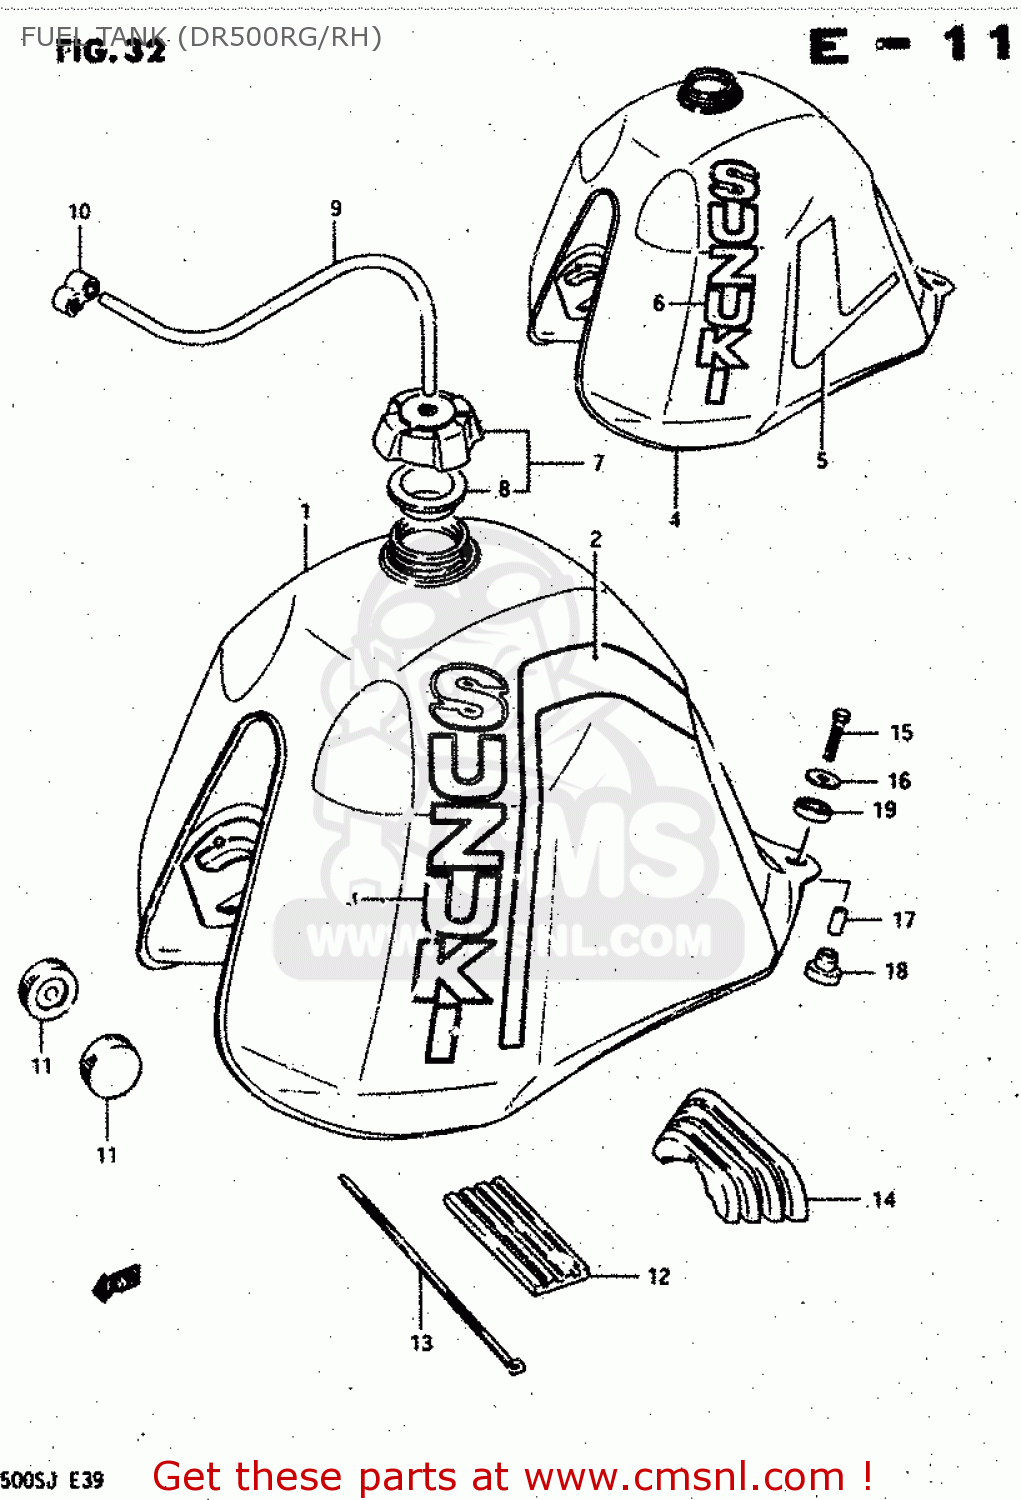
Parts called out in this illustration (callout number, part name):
1	TANK ASSY, FUEL
2	TAPE SET, FUEL TANK
3	EMBLEM
4	TANK ASSY, FUEL
5	TAPE SET, FUEL TANK (BLUE)
6	EMBLEM SET, FUEL TANK
7	CAP SET,FUEL TANK
8	GASKET,FUEL TANK CAP (NAS)
9	HOSE
10	CLAMP,FUEL TANK BREATHER HOSE
11	CUSHION
12	CUSHION,FUEL TANK UPR FR
13	CLAMP
14	CUSHION,FUEL TANK RR
15	BOLT
16	WASHER (6.5X24X1.6)
17	SPACER
18	CUSHION
19	CUSHION
